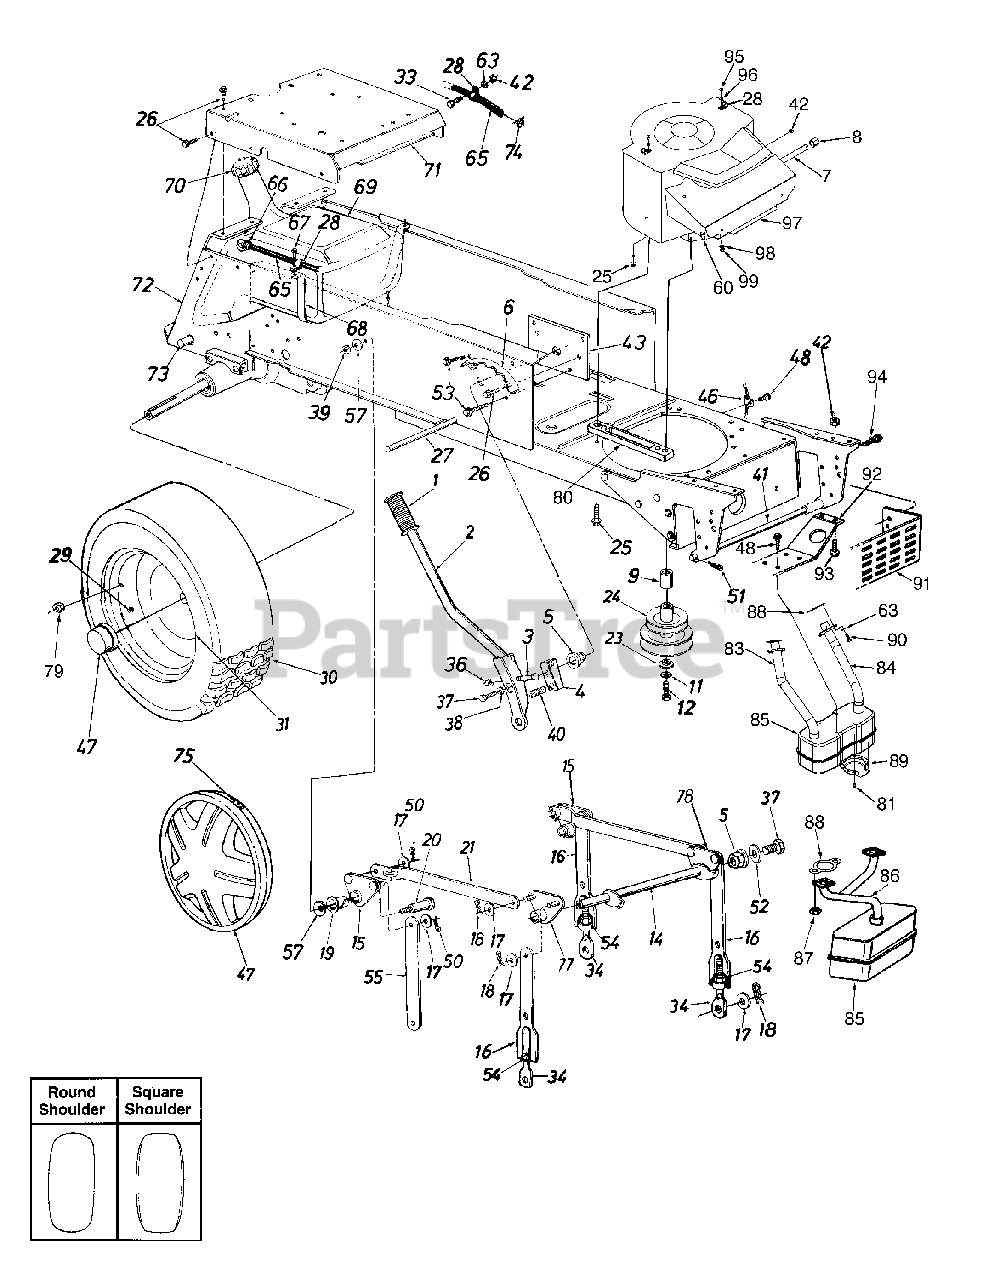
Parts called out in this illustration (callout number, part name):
1	Grip
4	Lift Shaft Drive
5	Plastic Hex Brg. 5/8" I.D.
8	Pipe Cap 3/8-18 Npt.
9	Spacer
11	L-Wash. 7/16" I.D.
12	Hex Scr. 7/16-20 x 2" Lg. (Gr. 5)
14	Lift Shaft Ass'y.
15	Lift Pivot Brkt. Ass'y.
17	Flat Washer
18	Hairpin Cotter
19	Nyliner 5/8" I.D. x .88" Lg.
20	Shld. Bolt 5/8" Dia. x .96" Lg. 3/8-16
24	Engine Pulley
25	Hx Wash Hd. Scr. 3/8-16 x 1.25"
26	Hex Thd. Rolling Scr. 5/16-18 x .75"
27	Running Board Rod
28	Clamp
29	Air Valve
30	Rear Wheel Ass'y. Comp.
31	Rear Wheel Rim Only
33	Hex Bolt 1/4-20 x .62" Lg.
34	Eye Bolt Adj. Link 1/2-13 Thd.
36	Hex Cent. L-Nut 5/16-18 Thd.
37	Hex Bolt 5/16-24 x .62" Lg.
38	L-Wash. 5/16" I.D.
39	Hex Top L-Nut 3/8-16 Thd.
40	Compression Spring
41	Deck Connecting Rod
42	Hex Sems Nut 1/4-20 Thd.
47	Hub Cap
48	Hx Wash Hd. TTScr. 1/4-20 x .5" L
50	Cotter Pin .09 Dia. x 1.0" Lg.
51	Int. Cotter Pin
52	Flat Washer
53	Hx Wash Hd AB-Tap Scr
54	Hex Nut 1/2-13 Thd.
57	Bell-Wash. .4" I.D. x 1.13" O.D.
60	Hex Bolt 5/16-18 x .75" Lg.
63	L-Wash. 1/4" I.D.
65	Fuel Line 46" Lg.
66	Hose Clamp
67	Hex AB-Tap Scr. 1/4 x .62" Lg.
68	Fuel Tank Strap
69	Gas Tank
70	Gas Gauge
71	Seat Plate
74	Hose Clamp
75	Spring Clip
77	Pivot Brkt. Ass'y.-R.H.
78	Pivot Brkt. Ass'y.-L.H.
79	Lug Nut 7/16-14 Thd.
80	Engine Mounting Spacer
81	Hex Hd. F-Tap Scr. #8-32 x .38"
83	Exhaust Tube-R.H.
84	Exhaust Tube-L.H.
85	Muffler
86	Exhaust Pipe
87	Flange Nut M8 x 1.25 Thd.
88	Exhaust Gasket
89	Muffler Deflector
90	Hex Bolt 1/4-20 x .75" Lg.
93	Hex Bolt 1/4-20 x .62" Lg.
94	Hex TT-Tap Scr. 5/16-18 x .62" Lg.
95	Truss Mach. B-Tap Scr. #10 x .5"
96	Fl-Wash. .188" I.D. x .438" O.D.
99	Hex Nut 5/16-18 Thd.
